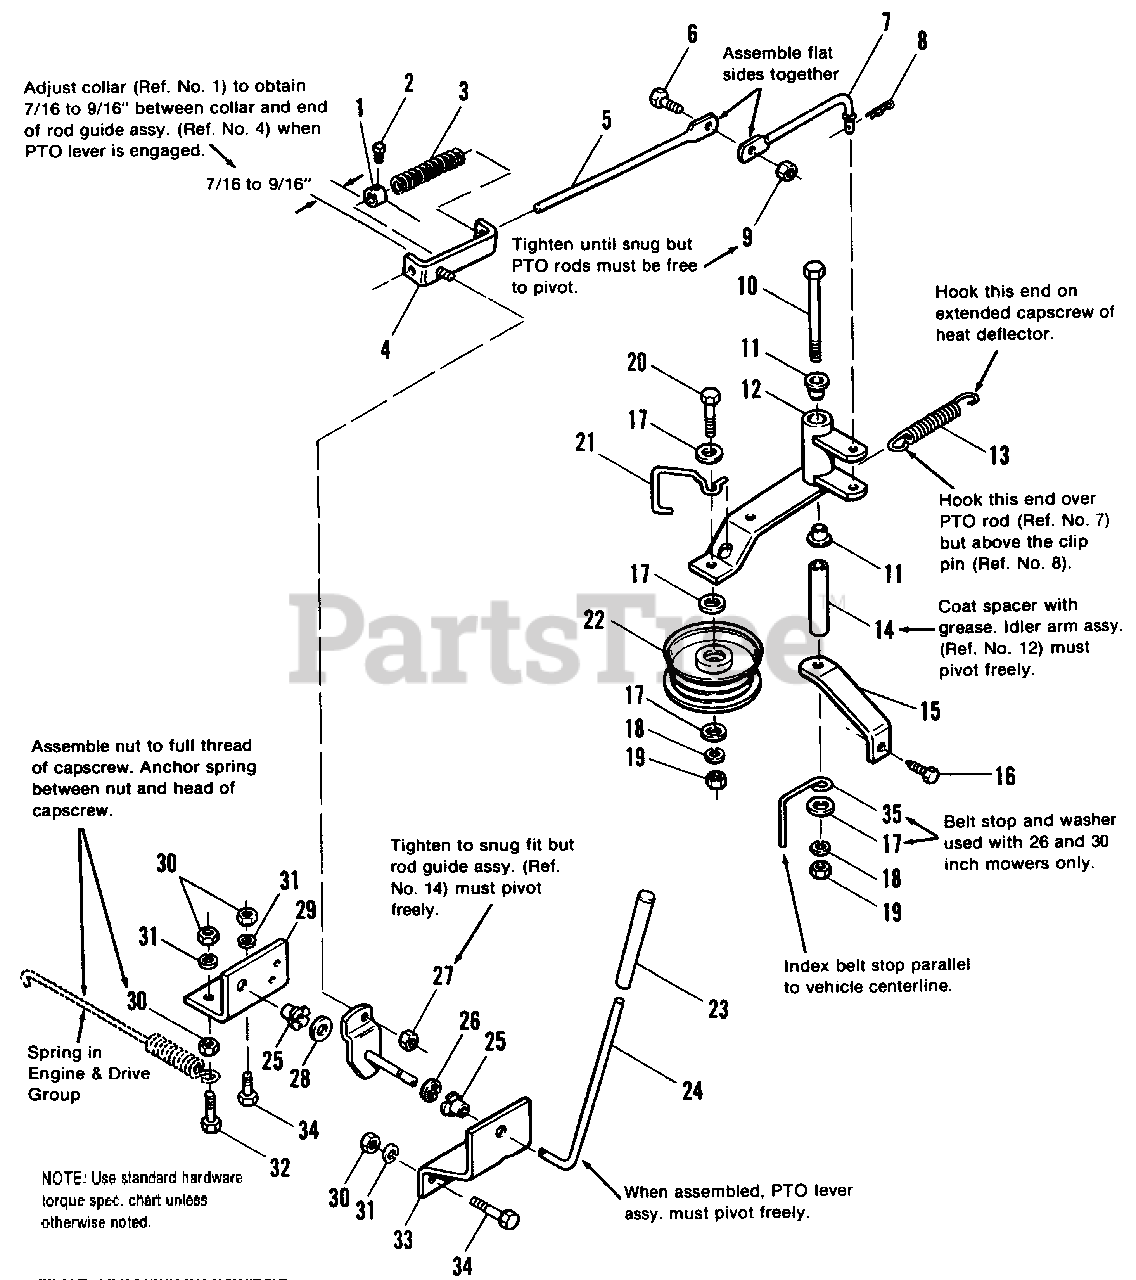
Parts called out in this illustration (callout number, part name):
1	COLLAR, Set
2	SETSCREW, 1/4-20 x 3/8
4	ROD GUIDE ASSY.
5	ROD, P.T.O. Front
6	CAPSCREW, Hex, 1/4-20 x 1/2
7	ROD, P.T.O., Rear
8	CLIP, Hairpin
9	LOCKNUT, Hex, 1/4-20 x 1/2
10	CAPSCREW, Hex, 3/8-16 x 4
12	P.T.O. IDLER ARM ASSY.
13	SPRING, Return
15	SUPPORT, P.T.O.
16	SCREW, Taptite, 5/16-18 x 1/2
17	WASHER, Plain, 3/8
18	LOCKWASHER, 3/8
19	NUT, Hex, 3/8-16
20	CAPSCREW, 3/8-16 x 1-1/2
22	PULLEY, Idler
24	P.T.O. LEVER ASSY.
26	RING, Retaining
27	LOCKNUT, Hex, 5/16-18
28	WASHER, Plain, 17/32
29	SUPPORT, Inner
30	NUT, Hex, Full, 5/16-18
31	LOCKWASHER, 5/16
32	CAPSCREW, Hex, 5/16-18 x 1-1/2
33	SUPPORT, Outer
34	CAPSCREW, Hex, 5/16-18 x 5/8
35	STOP, belt (5 & 8 HP Only)
